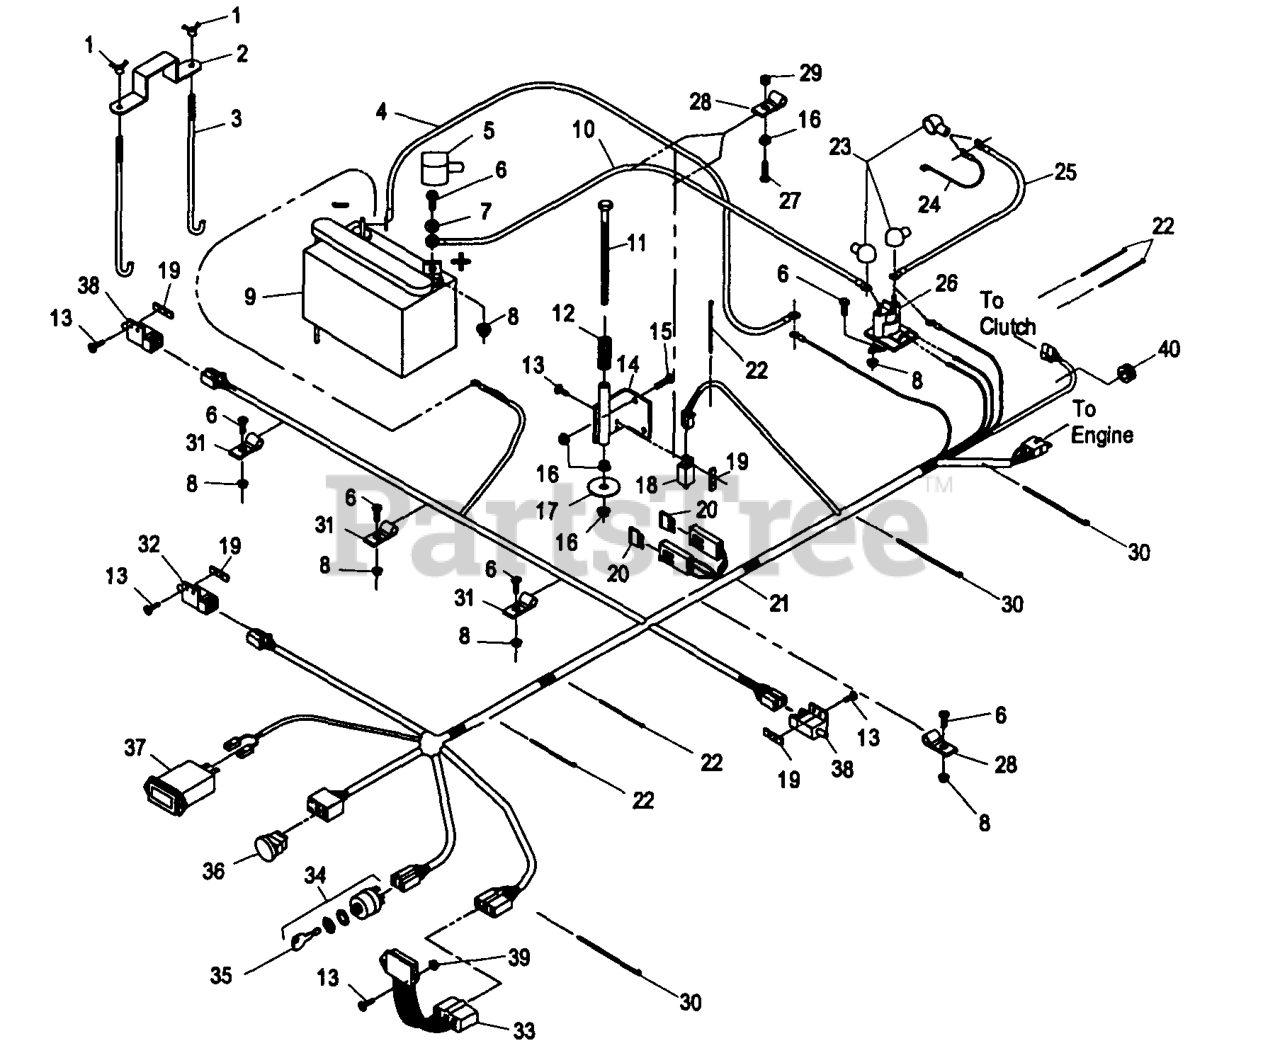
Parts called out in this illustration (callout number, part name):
1	WINGNUT
2	STRAP-HOLDDOWN
3	BOLT-HOLDDOWN
9	Battery, 12v
11	SCREW-HH
12	SPRING-SWITCH, SEAT
14	BRACKET-SWITCH, SEAT
18	SWITCH-CLOSED, NORMALLY
19	PLATE-TAPPED
20	FUSE-BLADE TYPE, 20 AMP
21	HARNESS,WIRING
22	TIE-CABLE
23	INSULATOR-SOLENOID
27	BOLT-TAP, HH
28	CLIP-LOOM
30	TIE-PLASTIC
31	CLIP-LOOM
32	SWITCH-BRAKE
33	MODULE,OPC
34	SWITCH,IGNITION
35	KEYS-IGNITION (SPARE PAIR
37	METER-HOUR
40	GROMMET
